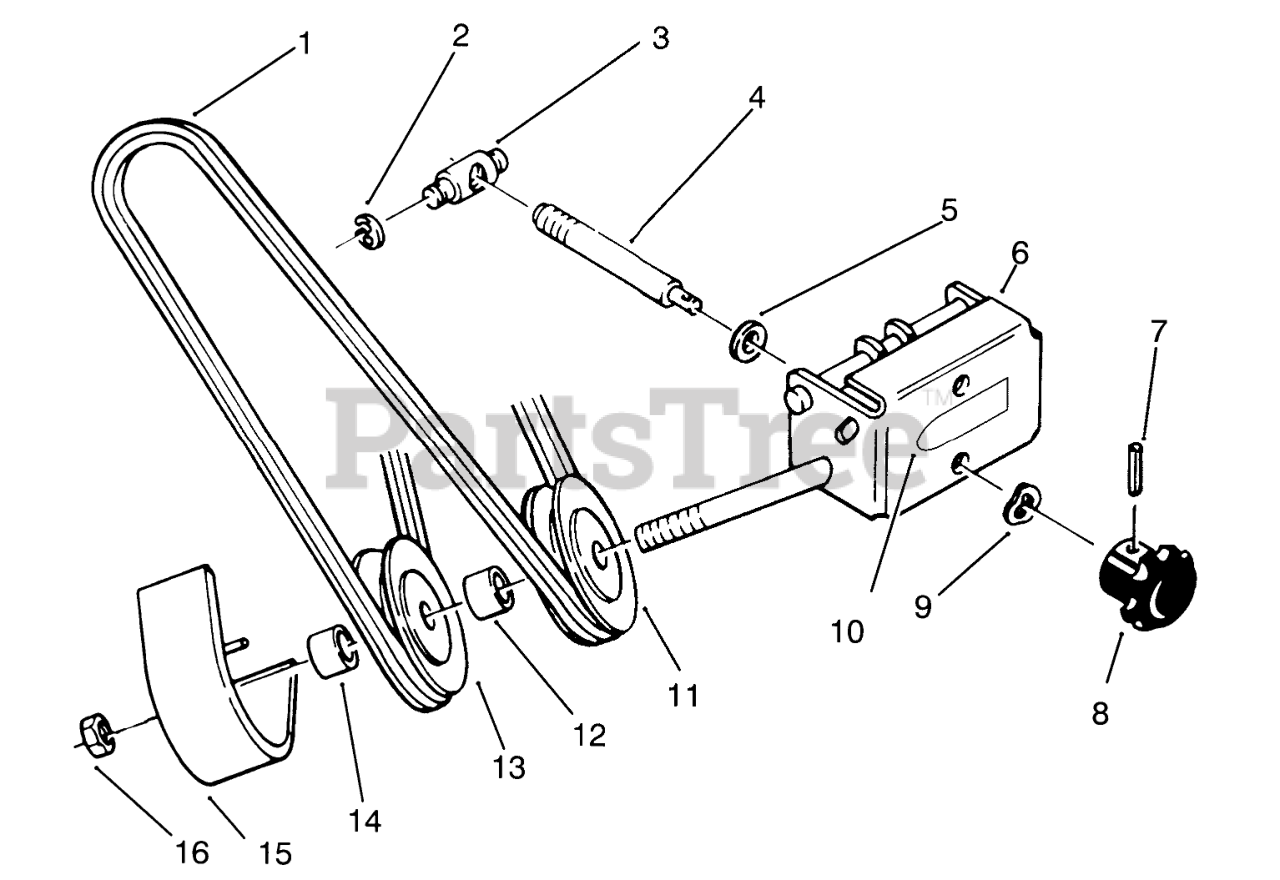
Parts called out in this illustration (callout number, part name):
1	V-BELT
2	RING-RETAINING
3	TRUNNION-DOUBLE
4	ROD ADJ
5	WASHER-FLAT
6	Front Support
7	PIN-ROLL
8	KNOB-ADJUSTMENT
9	WASHER-SPRING
10	DECAL-ATTACH A-MATIC
11	PULLEY-IDLER
12	SPACER
13	PULLEY-FLAT IDLER
14	SPACER-OUTER
15	Belt Cover
16	Nut
